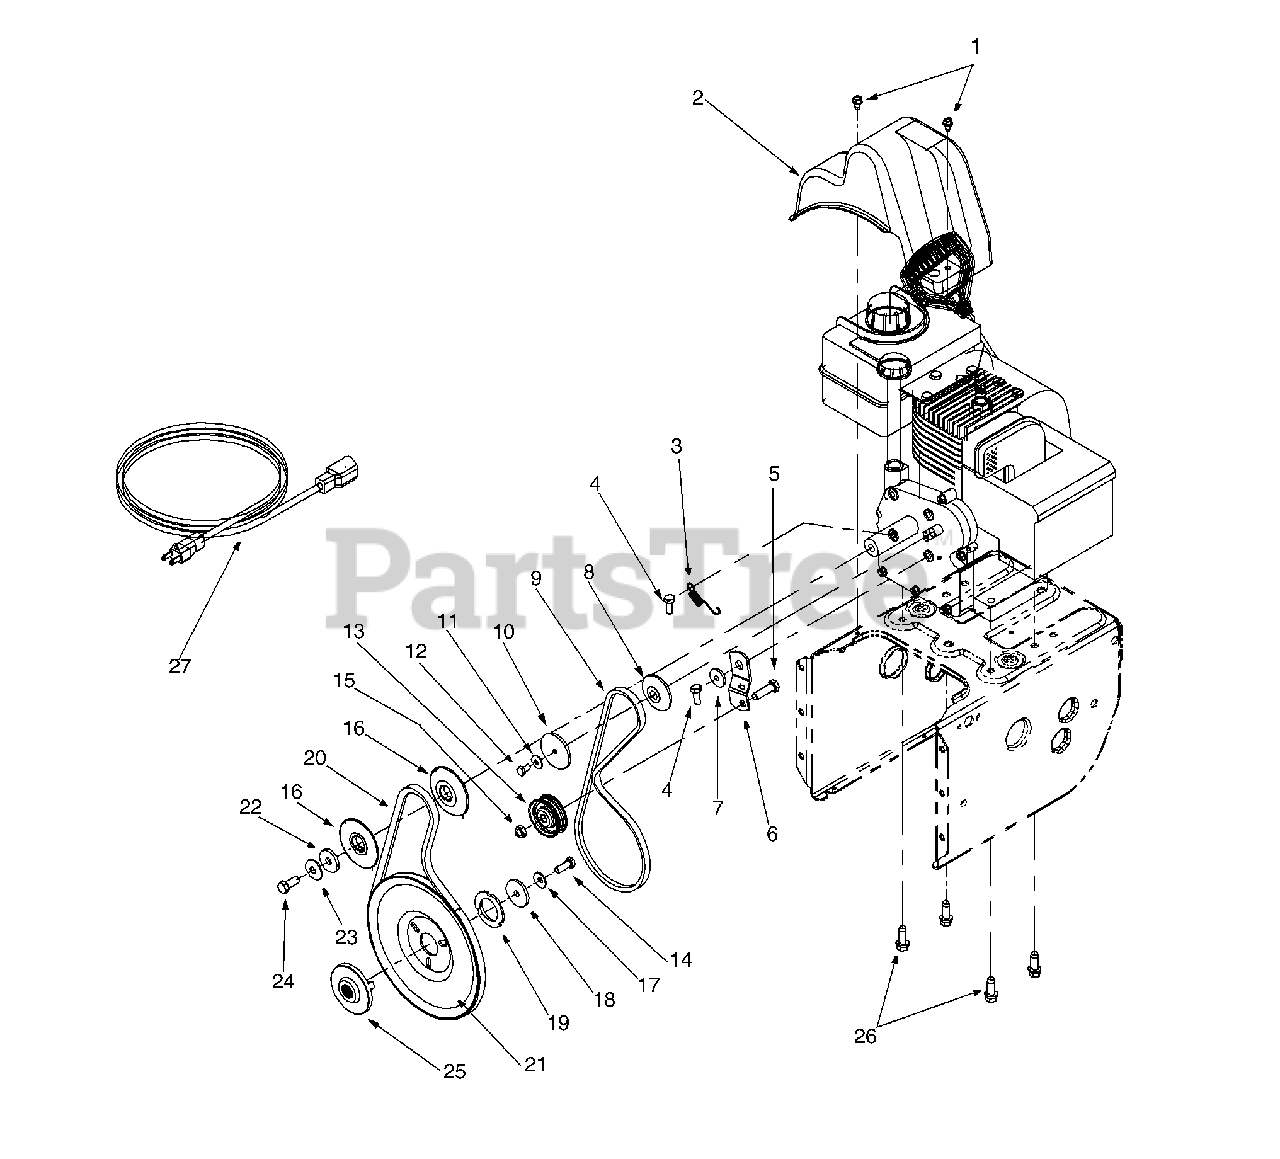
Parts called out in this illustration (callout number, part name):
1	Hex Washer Screw 1/4-20 x.5
2	Belt Cover
3	Extension Spring
4	Hex Screw 5/16-24 x .75
5	Hex Cap Screw 3/8-16 x 1.25
8	Pulley Half
9	V-Belt
10	Pulley Half
11	Bell Washer
12	Hex Cap Screw 1/4-28 x .50
13	Flat Idler
14	Lock Cap Screw 5/16-24
15	Lock Jam Nut 3/8-16
16	Pulley Half
17	Bell Washer
18	Flat Washer
19	Washer
20	Belt
21	Auger Pulley
22	Flat Washer
23	Bell Washer
24	Hex Cap Screw 3/8-24
25	Pulley
26	Hex Washer Screw 3/8-16 x 1.0
27	Extension Cord
